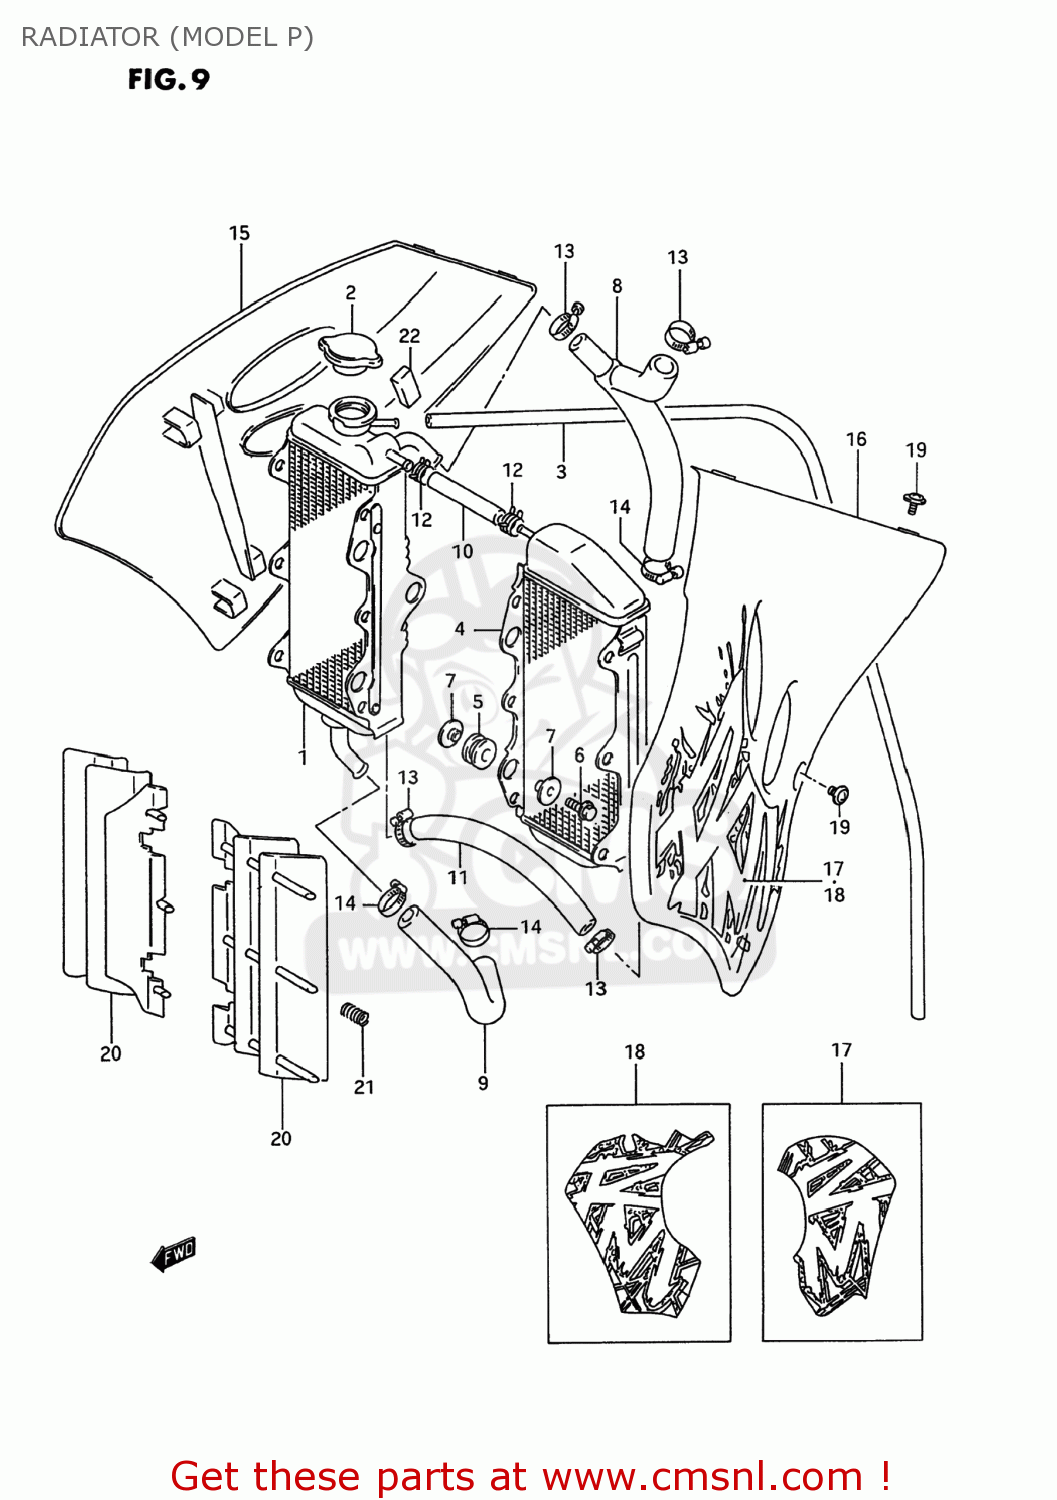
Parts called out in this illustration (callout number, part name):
1	RADIATOR ASSEMBLY,WATER
2	CAP,RADIATOR 1.1
3	HOSE
4	RADIATOR ASSEMBLY,WATER
5	CUSHION,RADIATOR LWR
6	BOLT
7	WASHER,RDTR SPRT
8	HOSE,RADIATOR INLET
9	HOSE,RADIATOR OUTLET
10	HOSE,WATER
11	HOSE,RADIATOR JOINT NO.2
12	CLIP
13	CLAMP
14	CLAMP
15	COVER,RADIATOR
16	COVER,RADIATOR
17	EMBLEM,RADIATOR COVER
18	EMBLEM,RADIATOR COVER
19	SCREW(6X12)
20	LOUVER,RADIATOR
21	SPRING
22	CUSHION,RADIATOR COVER
